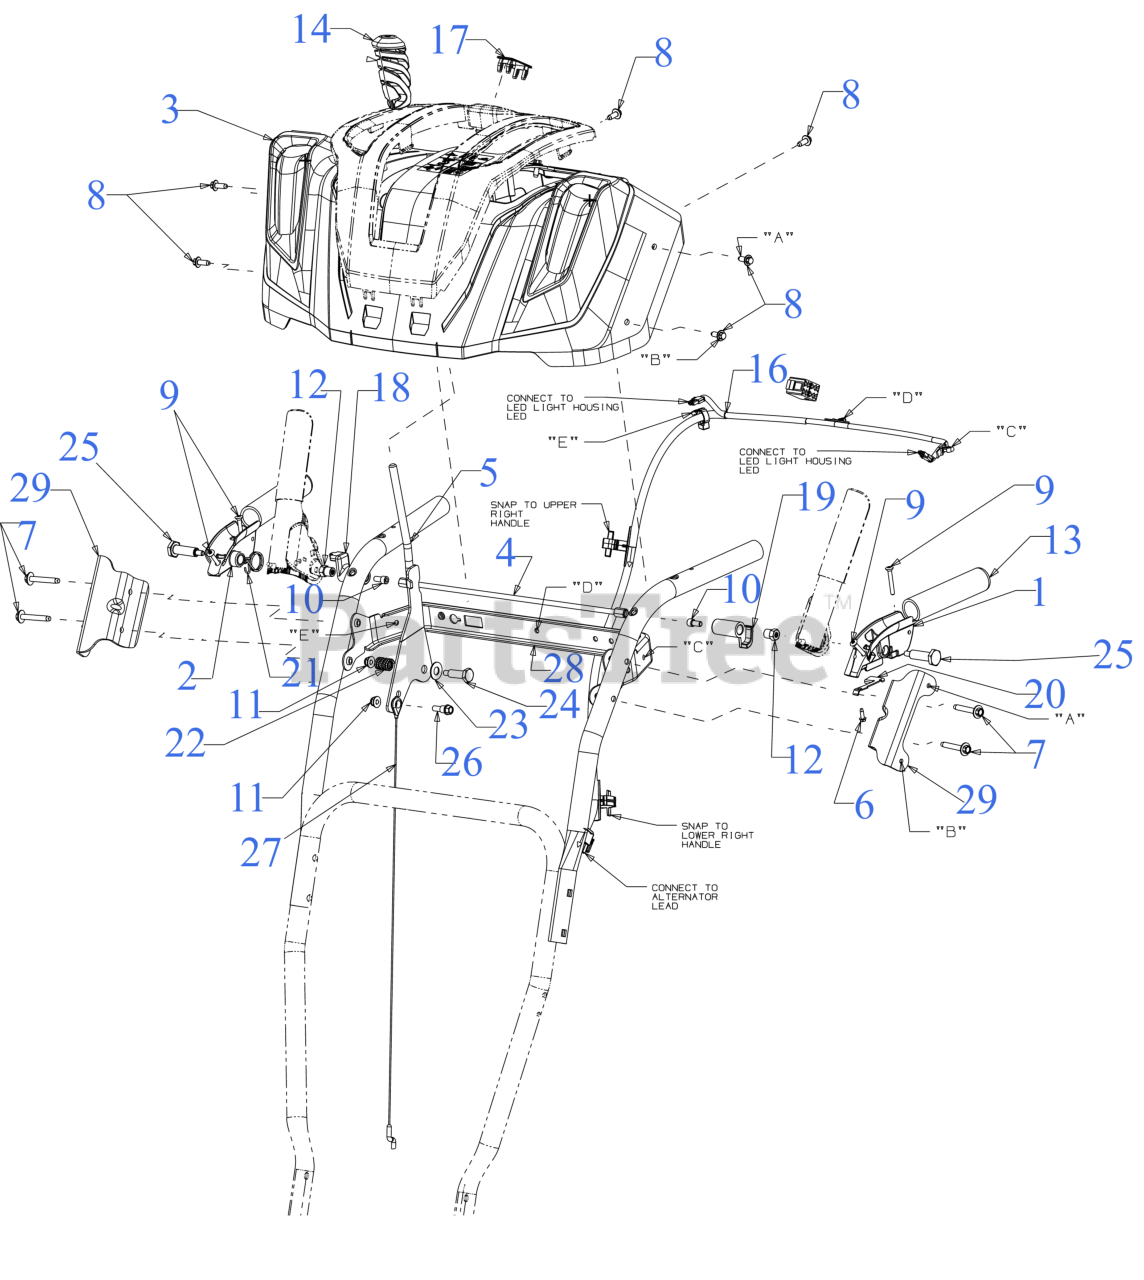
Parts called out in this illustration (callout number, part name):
1	CLUTCH LOCK HANDLE ASSEMBLY (LH)
2	CLUTCH LOCK HANDLE ASSEMBLY (RH)
3	Not Serviceable/ Components Only
3	HANDLE PANEL ASSEMBLY
3	SCREW M6-1 x .625
3	LED HEADLIGHT HARNESS ASSEMBLY
3	LENS-LED SNOW
3	SCREW 8/16X.500
6	SCREW #8-16 x .50
7	SCREW 1/4-20 x 1.625
8	SCREW M6-1 x .625
9	SCREW #10-24 x 1.375
10	SCREW 1/4-20 x .50
11	FLANGE LOCK NUT
12	HEX NUT W/PATCH
14	PTO HANDLE GRIP .355 ID
16	2 HEADLIGHT HARNESS
17	PANEL SWITCH PLUG
19	CLUTCH LOCK CAM
20	CLUTCH SPRING
21	TORSION SPRING
22	COMPRESSION SPRING
23	FLAT WASHER .401X.88
24	SHOULDER SCREW
25	SHOULDER SCREW .437 x 1.345 1/4-20
26	SHOULDER SCREW .342X.335X1/4-20
27	SELECTION CABLE
